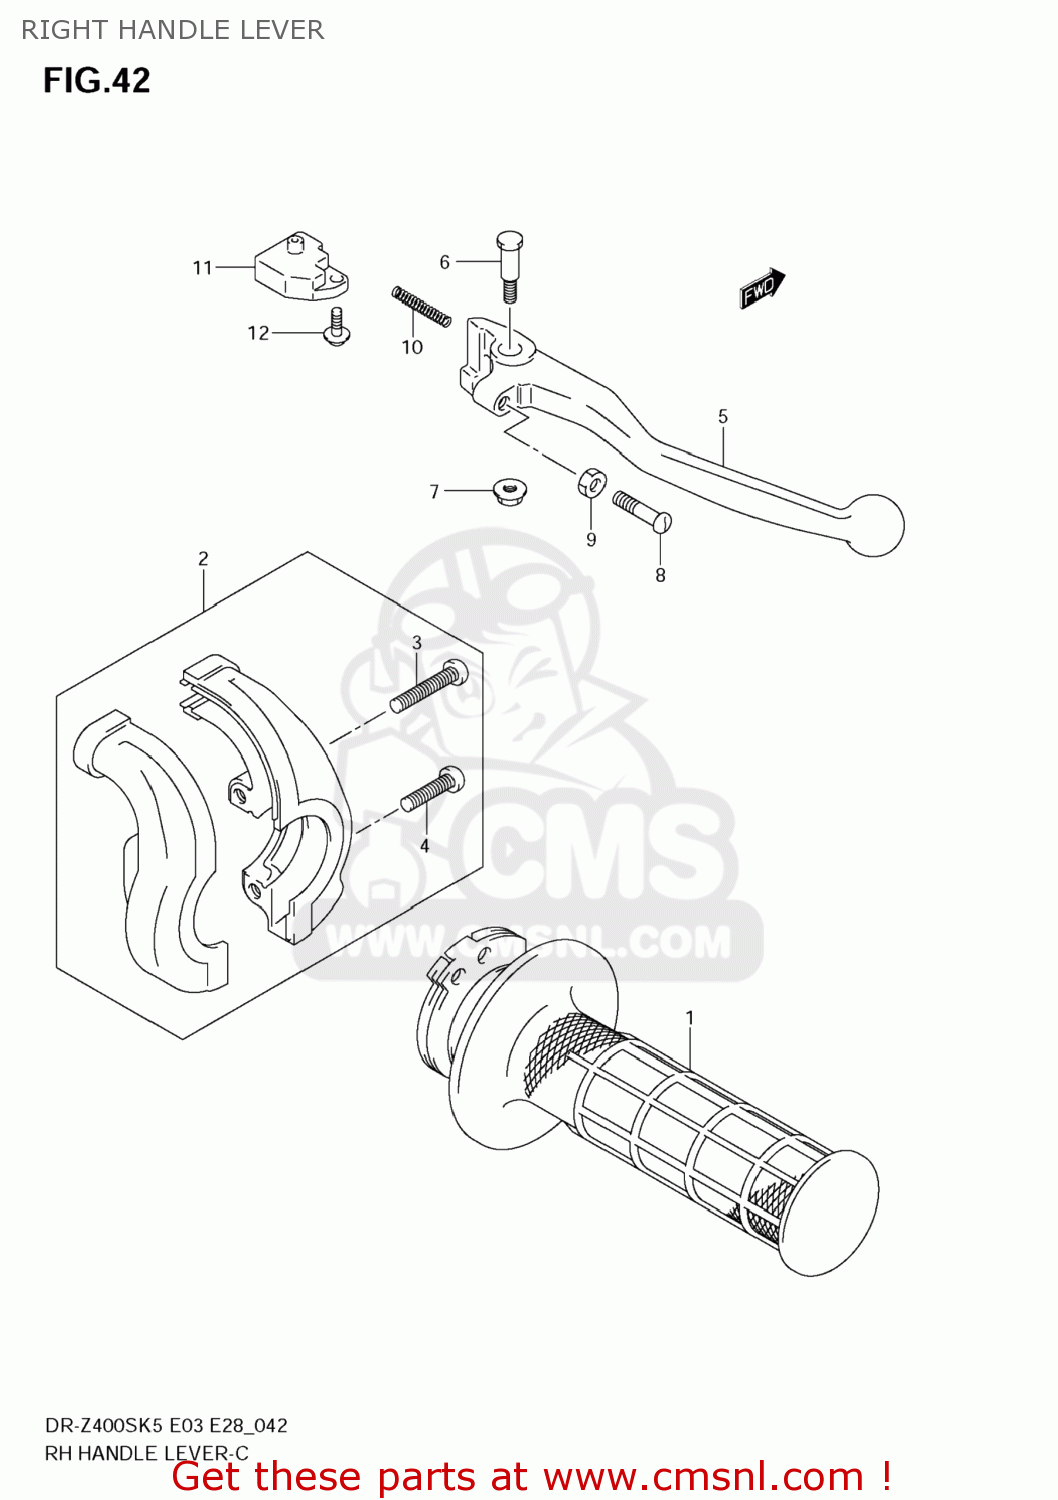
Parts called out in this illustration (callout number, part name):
1	GRIP,THROTTLE
2	CASE ASSY,THROTTLE
3	SCREW(5X25)
4	SCREW
5	LEVER,BRAKE
6	BOLT,BRAKE LEVER
7	NUT
8	BOLT,ADJUST
9	NUT
10	SPRING,RETURN
11	SWITCH ASSY,ST
12	SCREW
